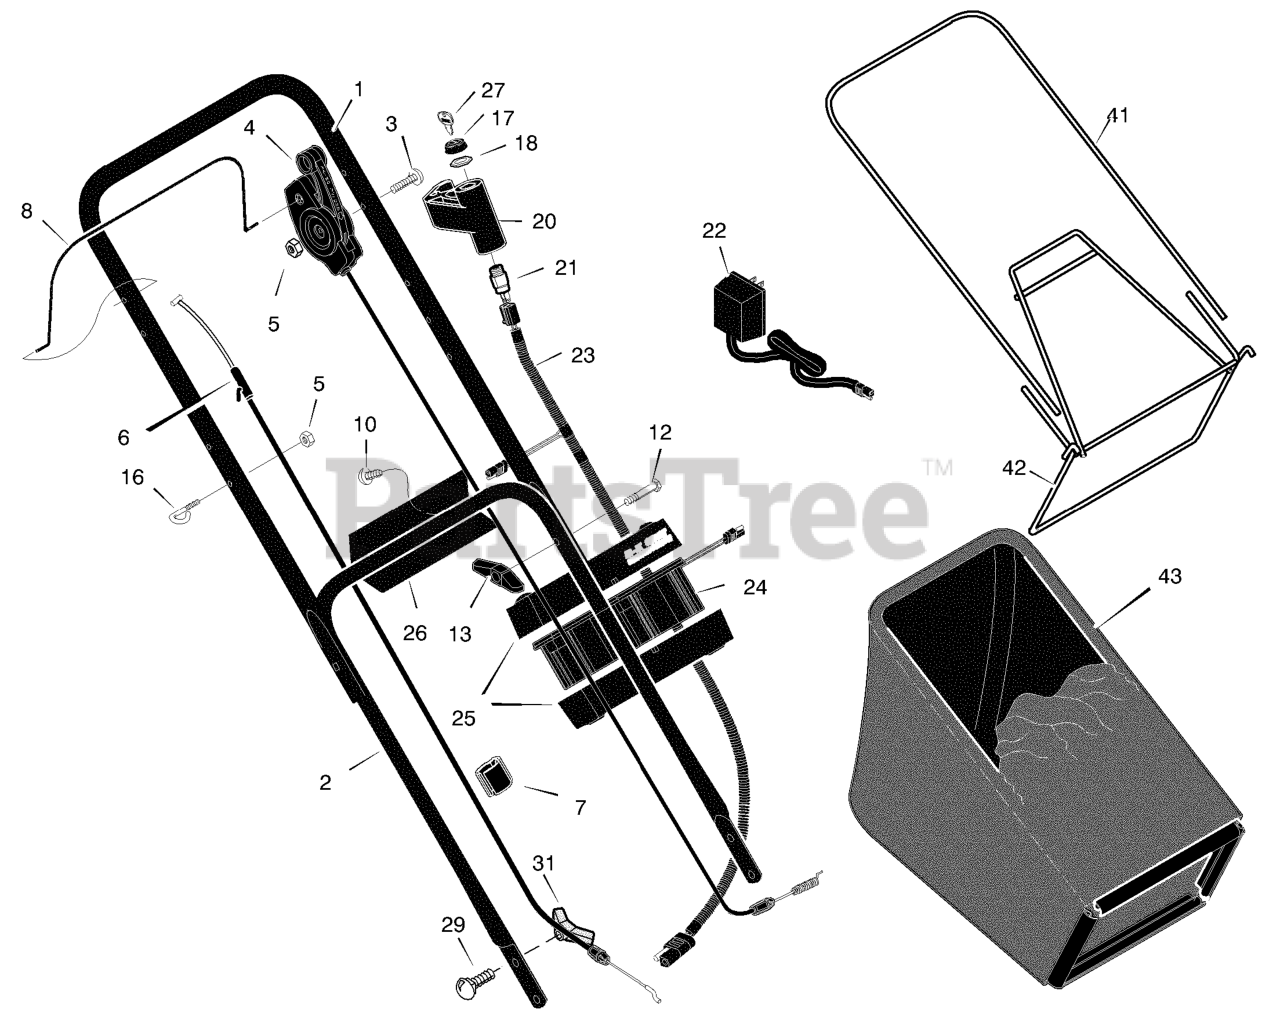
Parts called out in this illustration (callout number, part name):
1	Handle, Upper
2	Handle, Lower
4	Control, Drive
5	Locknut
6	Cable, Stop
7	Fastener, Cable
8	Lever, Stop
13	Knob
16	Guide, Rope
17	Cap
18	Nut
20	Case, Ignition
21	Switch Ignition & Key
22	Charger, Battery
23	Harness, Wiring
24	Battery
25	Case, Battery
26	Bracket, Battery
27	Key, Ignition
29	Bolt, Carriage
31	Knob, Plastic
41	Frame, Top
42	Frame Assembly
43	Bag, Cloth
